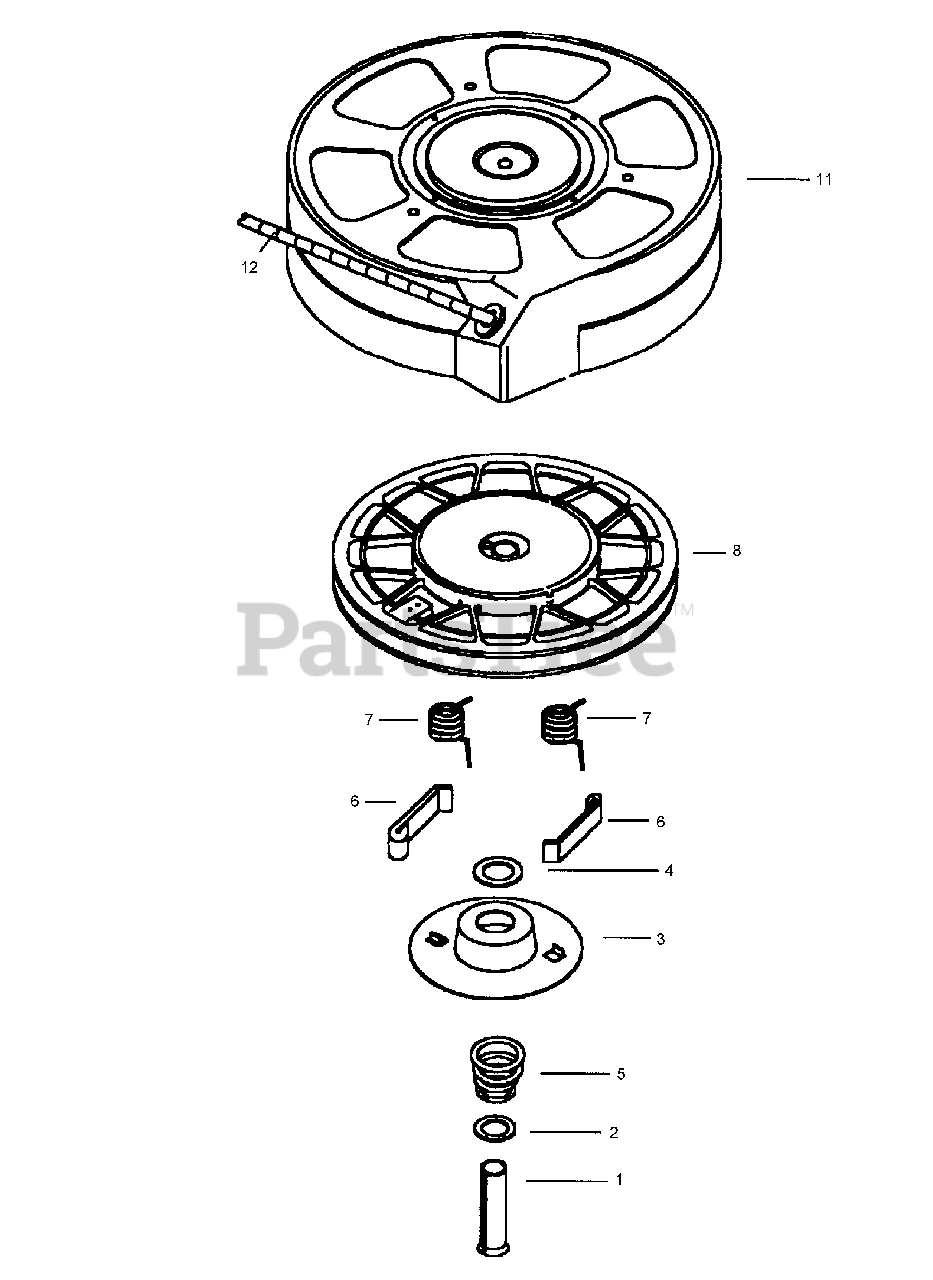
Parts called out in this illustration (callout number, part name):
1	Spring Pin ASM
2	Washer
3	Retainer
4	Washer
5	Spring-Brake
6	Dog-Starter
7	Spring-Dog
8	Pulley and Rewind Spring ASM
11	Starter Housing ASM
12	Rope-Starter (98in X 9/64in diameter)
